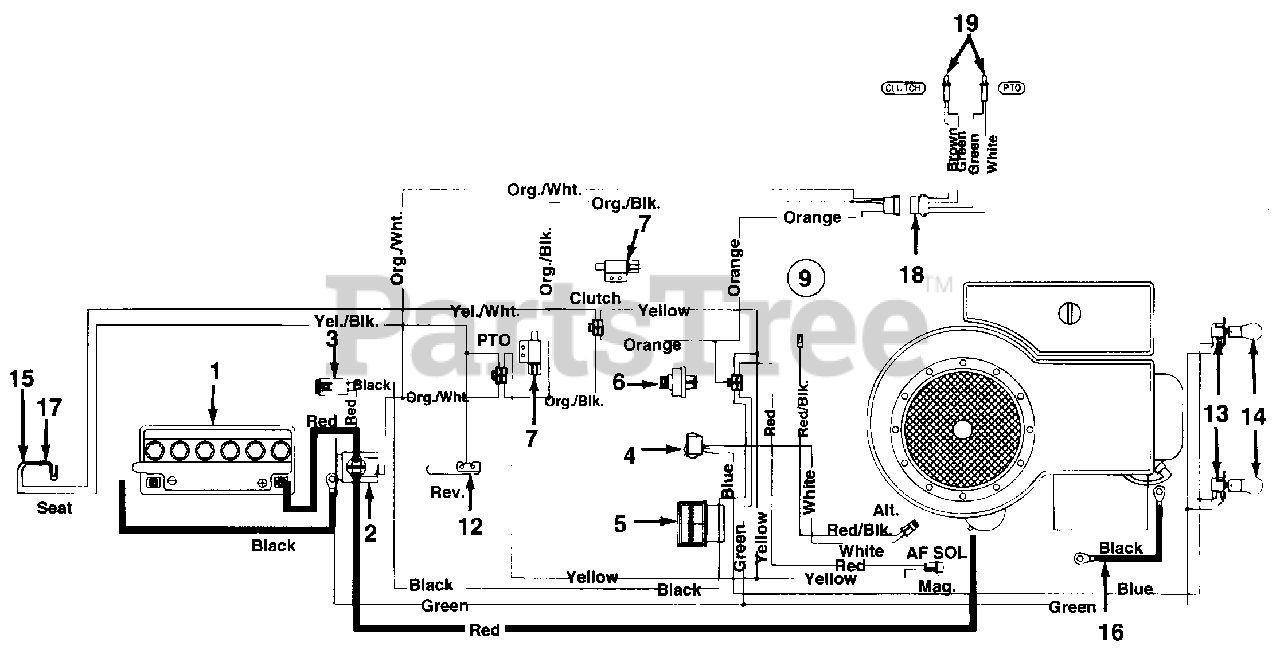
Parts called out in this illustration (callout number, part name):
1	Battery
2	Solenoid
3	Fuse 7.5 Amps
4	Light Switch
5	Ammeter
6	Ignition Switch
7	Safety Switch (Clutch)
9	Wire Harness
12	Safety Switch (Reverse)
13	Socket
14	Bulb (Headlight)
15	Safety Switch (Seat)
16	Ground Wire 7.5" Lg.
17	Safety Switch (Seat)
18	Monitor Harness
19	Monitor Bulb
